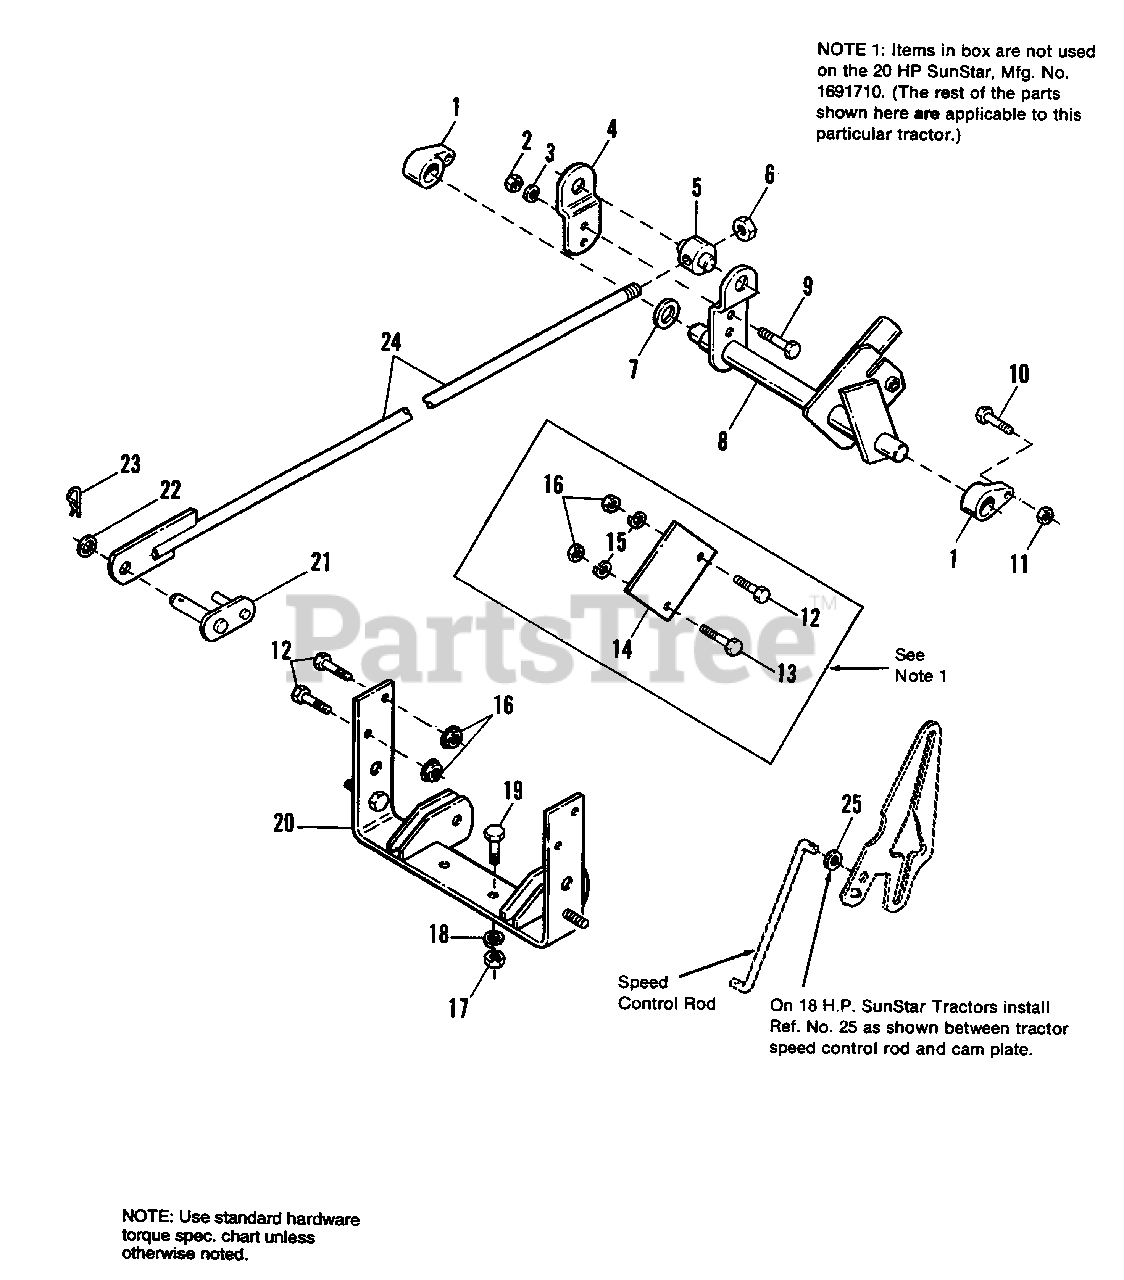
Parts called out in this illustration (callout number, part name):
2	NUT, Hex, 3/8-16
3	LOCKWASHER, 3/8
4	ARM, Lift
6	NUT, Hex, Lock, 1/2-13
7	WASHER, Plain, 1 x 1-3/8 x 1/16
8	SHAFT ASSY., Lift
9	CAPSCREW, Hex Hd., 3/8-16 x 1
10	CAPSCREW, Hex Hd., 5/16-18 x 1-1/4
11	NUT, Hex, Centerlock 5/16-18
12	CAPSCREW, Hex Hd., 7/16-14 x 1-1/4
13	CAPSCREW, Hex Hd., 7/16-14 x 1-1/2
14	PLATE, End
15	LOCKWASHER, 7/16
16	NUT, Hex, Flange Whizlock, 7/16-14
17	NUT, Hex, 1/2-13
18	LOCKWASHER, 1/2
19	CAPSCREW, Hex Hd., 1/2-13 x 1-1/2
20	BRACKET ASSY., Hitch
21	CYLINDER PIN ASSY.
22	WASHER, Plain, 41/64 x 1-1/4 x 1/16
23	CLIP, Hair Pin, 1/8 x 2-9/16
24	ROD ASSY., Lift
25	WASHER, Special
